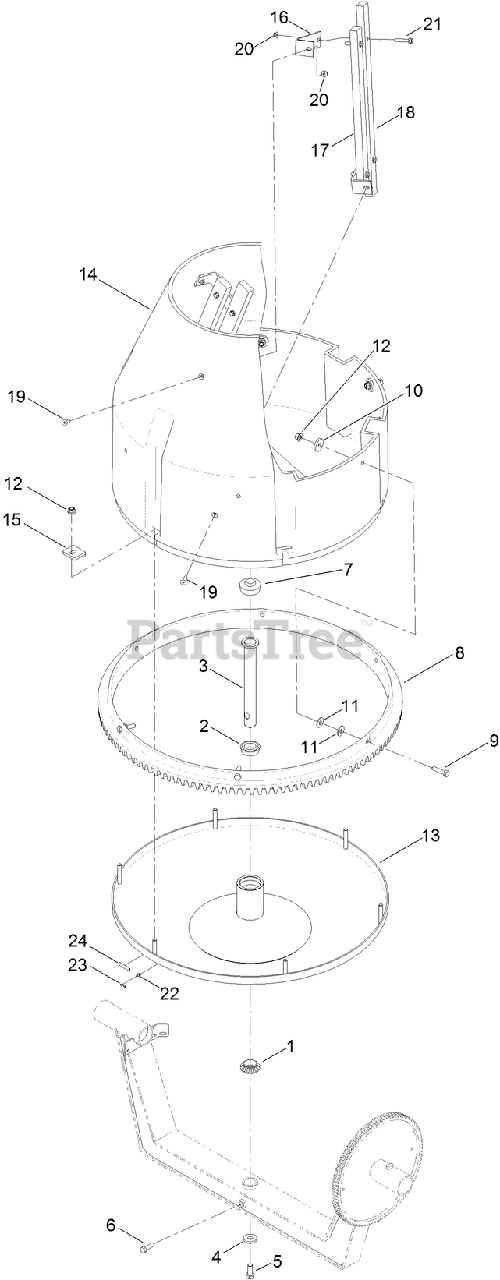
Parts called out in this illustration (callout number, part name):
1	BEARING-ROLLER
2	BEARING
3	SPINDLE
4	WASHER-FLAT
5	SCREW-HH
6	SCREW-HH
8	GEAR-RING
9	SCREW-HH
10	WASHER-FLAT
11	WASHER-FLAT
12	NUT-LOCK
14	DRUM
15	CLAMP-DRUM
16	BRACKET-PADDLE
17	PADDLE
18	PADDLE
19	SCREW-HSFH
20	NUT-HF, NI
21	SCREW-HHF
22	FITTING
23	CAP-PLUG
24	DECAL-GREASE
